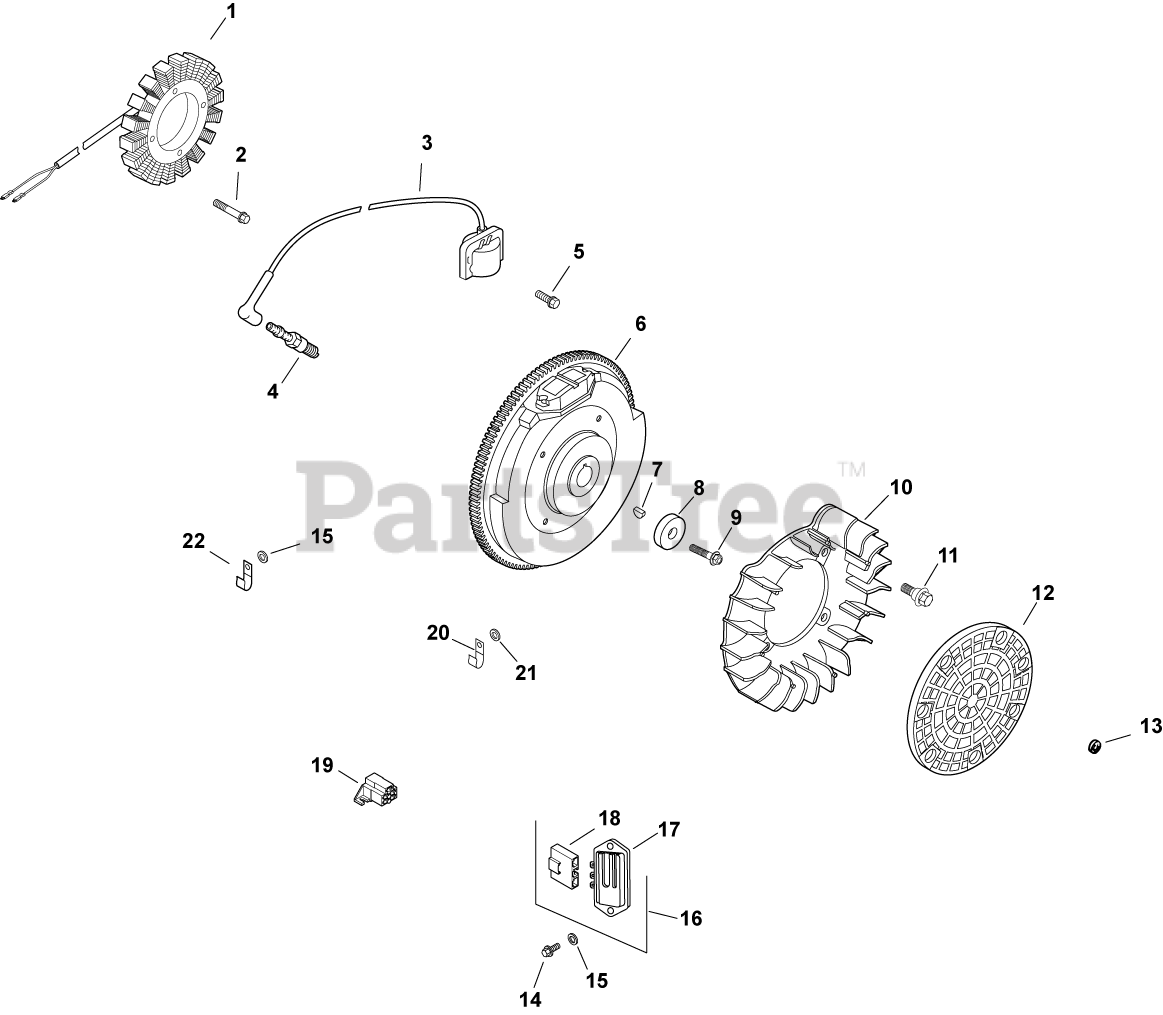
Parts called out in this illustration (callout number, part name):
1	KIT, 25 AMP STATOR ASSY.
2	SCREW, THD FROM M5X0.8X30
3	KIT, MODULE IGNTN (CDI FIXED)
4	PLUG, SPARK (STD)
5	SCREW, FLG THD FRM M5X.8X20-(#25086399S)
6	FLYWHEEL, PAINTED-USE 24 025 55-S
7	KEY, 3/16" X 5/8"
8	WASHER, FLAT 13/32"
9	SCREW, FLG M10X1.5X45 - (#25086361S)
10	FAN - USE (#24 157 11-S)
11	BOLT, SHOULDER
12	SCREEN, GRASS
14	SCREW, PHL HD #11-16X7/8"
15	WASHER, FLAT 7/32"
16	KIT, FULL WAVE CONVERSION
17	REG/RECTIFIER (20/25 AMP)-USE 25 403 20-
18	CONNECTOR, BODY (KM)-USE 25 155 41-S
19	CONNECTOR
20	CLIP, TUBE & WIRING (KM)
21	WASHER, FLAT 1/4" (O.D. 1/2")
22	CLIP, CABLE
